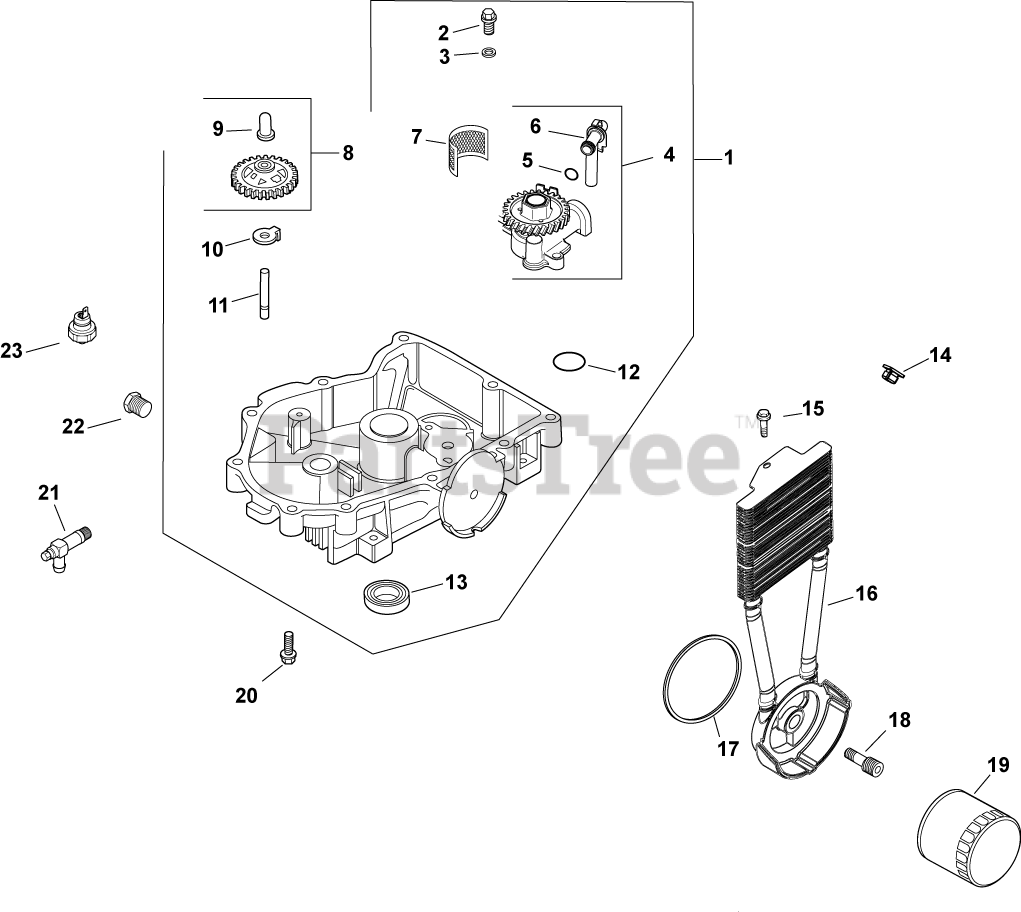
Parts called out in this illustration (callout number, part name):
1	PAN , OIL ASSEMBLY USE 24 199 32-S
2	SCREW,FLG THD FRM M6X1.0X25-(#25086395S)
3	WASHER, FLAT 6 MM
4	PUMP ASSEMBLY, OIL-USE 24 393 53-S
5	O-RING, OIL PICK-UP
6	KIT, OIL PICK-UP TUBE
7	SCREEN, OIL
8	KIT, GOVERNOR GEAR W/PIN
9	PIN, GOVERNOR REGULATING
10	TAB, LOCKING
11	SHAFT, GOVERNOR GEAR
13	SEAL, OIL
14	NUT, PLASTIC (KM)-USE 25 100 37-S
15	SCREW, TAP M6X1.7X18
16	KIT, OIL COOLER
17	O-RING, OIL COOLER
18	NIPPLE, OIL FILTER
19	OIL FILTER
20	SCREW, FLG M8X1.25X45
21	VALVE, OIL DRAIN MEDIUM
22	PLUG, HD PIPE 3/8"
23	SENSOR, OIL PSI
